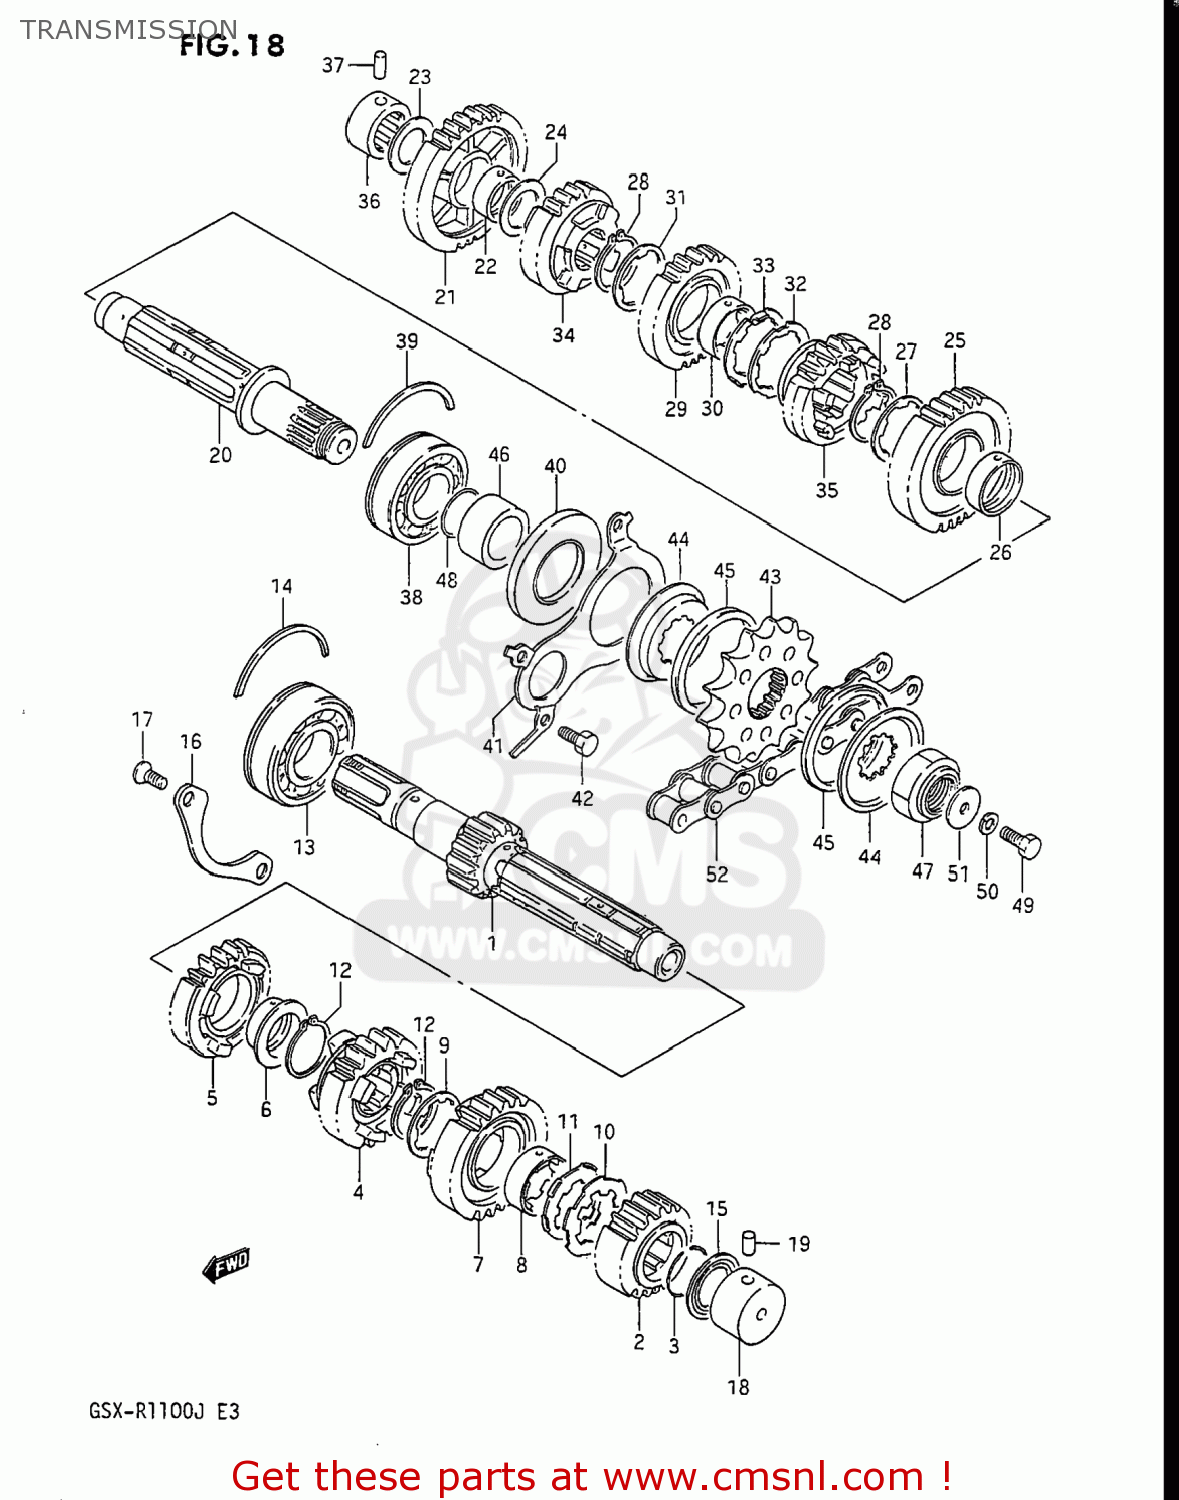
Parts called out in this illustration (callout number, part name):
1	SHAFT,COUNTER
2	GEAR,SECOND DRIVE
3	RING,SNAP
4	GEAR,THIRD DRIVE
5	GEAR,FOURTH DRIVE
6	BUSHING
7	GEAR,FIFTH DRIVE
8	BUSHING
9	WASHER,LOCK
10	WASHER,LOCK
11	WASHER
12	RING,SNAP
13	BEARING(25X62X17)
14	C-RING
15	SEAL,OIL(20X31.2X2.7)
16	RETAINER,CNTR SHAFT BEARING
17	SCREW
18	BEARING(20X34X17.5)
19	PIN
20	SHAFT,DRIVE
21	GEAR,FIRST DRIVEN
22	BUSHING
23	WASHER
24	WASHER
25	GEAR,2ND DRIVEN
26	BUSH(28X32X11)
27	WASHER
28	CIRCLIP
29	GEAR,THIRD DRIVEN
30	BUSH
31	WASHER,LOCK
32	WASHER,LOCK
33	WASHER
34	GEAR,FOURTH DRIVEN (NT:23)
35	GEAR,5TH DRIVEN
36	BEARING(20X34X20)
37	PIN
38	BEARING
39	C-RING
40	SEAL,OIL(34X62X6)
41	RETAINER,DRIVESHAFT O
42	BOLT
43	SPROCKET,ENGINE
44	HOLDER,SPROCKET DAMPER
45	DAMPER,ENGINE SPROCKET
46	SPACER (25X34X18.1)
47	NUT
48	O RING(D:1,ID:24.5)
49	BOLT
50	WASHER,LOCK
51	WASHER
52	CHAIN ASSEMBLY,DRIVE
